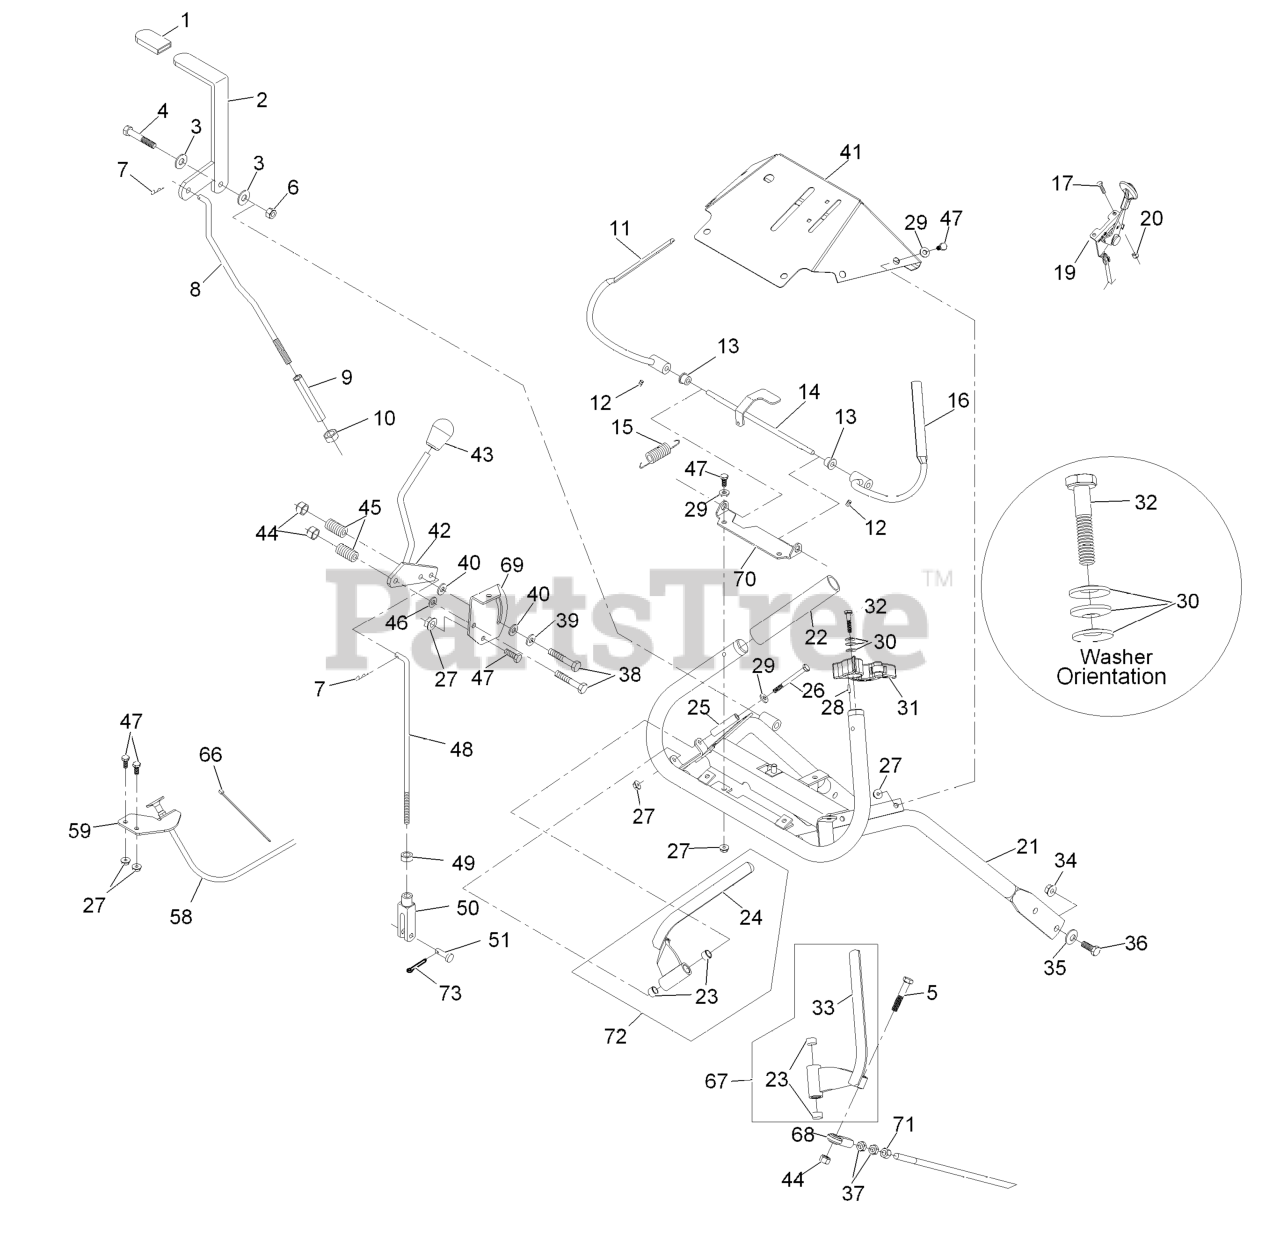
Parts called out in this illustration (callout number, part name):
1	GRIP-LEVER
3	WASHER-FLAT
4	SCREW-HH
5	SCREW-HH
6	NUT-LOCK, NI
7	PIN-COTTER
8	LINK,BLADE ENGAGE (PLTD)
9	TURNBUCKLE
10	NUT-HEX
11	WLD,LH OPC LEVER
12	SCREW-SET
13	BUSHING-NYLON
14	WLD,OPC LEVER AXLE
15	SPRING-EXTENSION
16	WLD,RH OPC LEVER
17	BOLT-CARR
19	CONTROL, THROTTLE
20	NUT-LOCK, NI
21	WLD,UPPER ECS HANDLE
22	GRIP-BAR, HANDLE
23	BUSHING-SLEEVE
24	Lever, Drive Lh
25	BUSHING-LEVER, DRIVE
26	SCREW-HH
29	WASHER-FLAT
30	WASHER-SPRING
31	ASM,LATCH RH THUMB
31	ASM,LATCH LH THUMB
32	SCREW-HH
33	Lever, Drive Rh
34	NUT-HHF, WHIZ
35	WASHER-BELLEVILLE
36	SCREW-HH
37	NUT-HJ
38	SCREW-HH
39	WASHER-FRICTION
40	WASHER-FRICTION
41	ASM,CONSOLE W/DECALS
43	KNOB, FE.LCKG. BLACK
44	NUT-LOCK, NI
45	SPRING-COMPRESSION
46	WASHER-PLAIN
47	SCREW-HH
48	ROD,SPEED CONTROL
49	NUT-JAM
50	YOKE-ADJUSTABLE
51	PIN-CLEVIS
58	CABLE-CHOKE
59	BRACKET-CABLE, CHOKE
66	TIE-CABLE
67	DRIVE LEVER-ASM, RH
68	JOINT-BALL, END
69	BRACKET,SHIFTER SLIDE (PL
70	BRACKET,OPC AXLE
71	NUT-HEX
72	DRIVE LEVER-ASM, LH
73	PIN-COTTER
